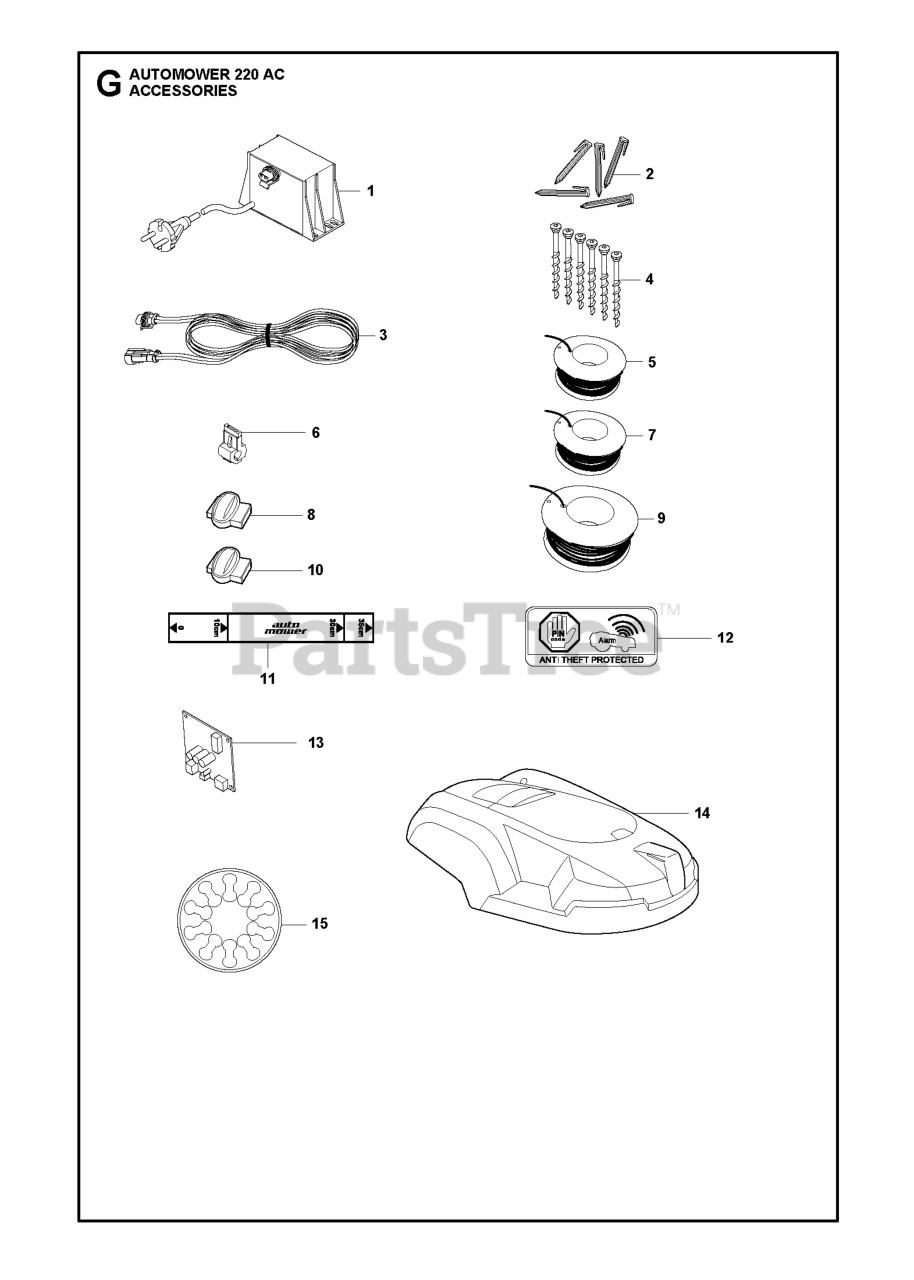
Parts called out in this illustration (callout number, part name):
1	TRANSFORMER
1	TRANSFORMER/US
2	STAPLES (100 CT BAG)
2	STAPLE 100 PCS, BLISTER
3	LOW VOLT WIRING
4	SCREW 3 PCS, BLISTER PACK
4	SCREW KIT CS
5	LOOP WIRE 150M
5	WIRE 150M, BLISTER
6	CONNECTOR 5 PCS, BLISTER
6	BRAKER
7	LOOP WIRE 250M
8	COUPLER SPLICER, 5 PCS,
8	SPLICE KIT
9	WIRE 500M
10	SPLICE CONNECTOR 50 PCS/PK
11	RULER / CENTIMETERS
13	PRINTED CIRCUIT ASSY
14	BODY AIR, CREAM WHITE
14	BODY EARTH, BROWN
14	BODY FIRE, ORANGE
14	BODY WATER, DARK BLUE
